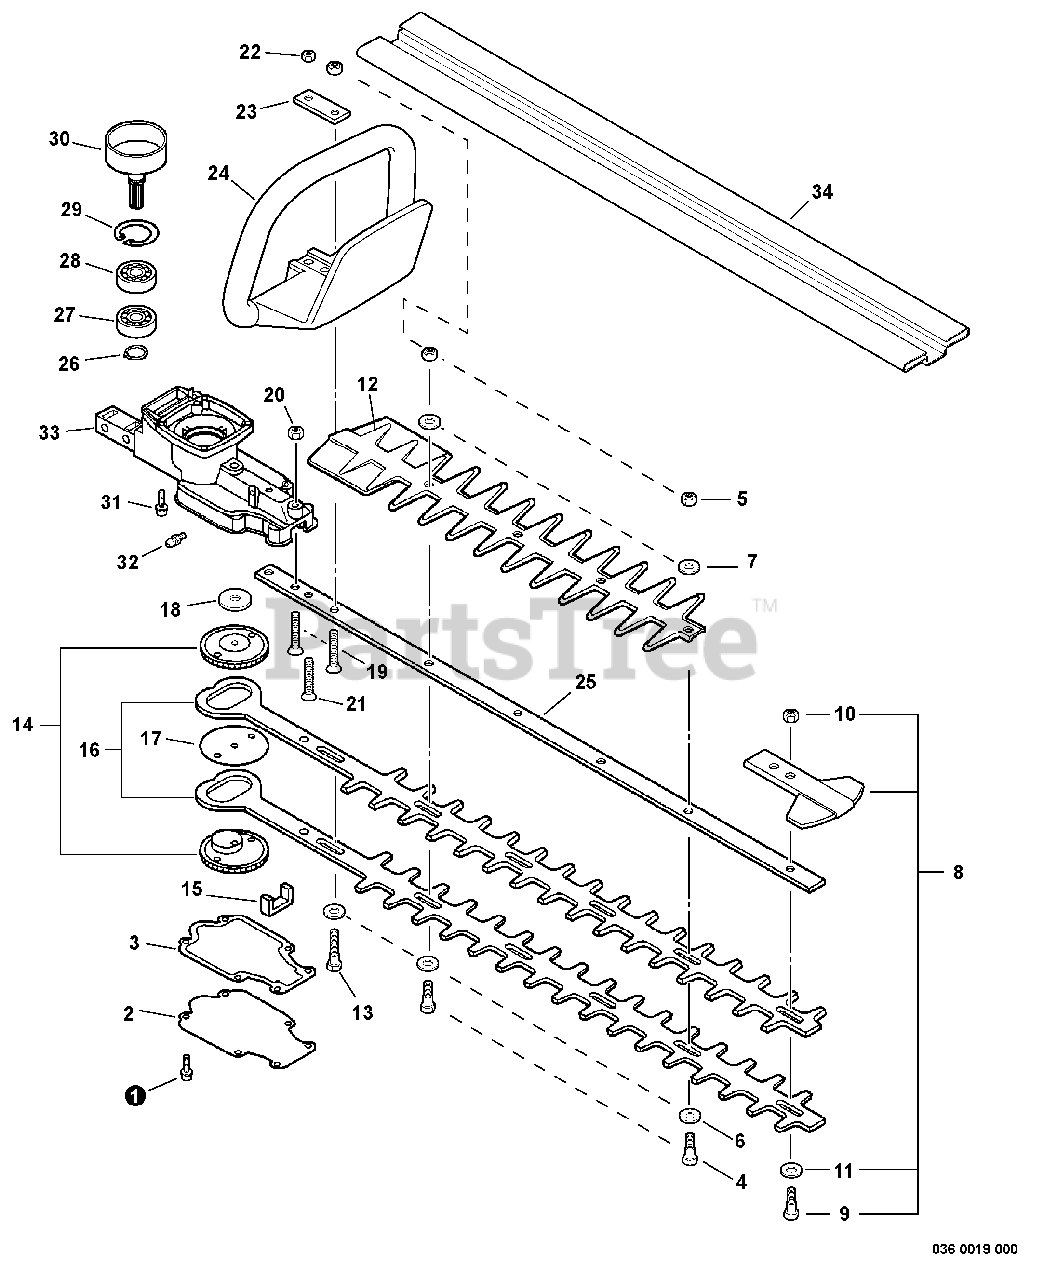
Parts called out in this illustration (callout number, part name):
1	SCREW - 4X12
2	LID, GEAR CASE
3	GASKET, GEAR CASE
4	BOLT - 6X18
5	LOCKNUT - 6
6	WASHER - 6
7	WASHER - 6
8	TIP GUARD KIT
9	BOLT - 6X20
10	LOCKNUT - 6
11	WASHER - 6
12	SHIELD, BLADE
13	BOLT - 6X35
14	GEAR - SPUR
15	SEAL, FELT
16	BLADE, TRIMMER
19	SCREW - 6X30
20	LOCKNUT - 6
21	SCREW - 5X30
22	LOCKNUT - 5
24	HANDLE - FRONT
25	SUPPORT, BLADE
26	RING, RETAINING - 14
27	BEARING, BALL - 6202
28	BEARING, BALL - 6202
29	RING, RETAINING - 35
30	DRUM, CLUTCH
31	SCREW - 4X16
32	FITTING, GREASE
33	CASE, GEAR
34	COVER, BLADE - 20" (50cm)
